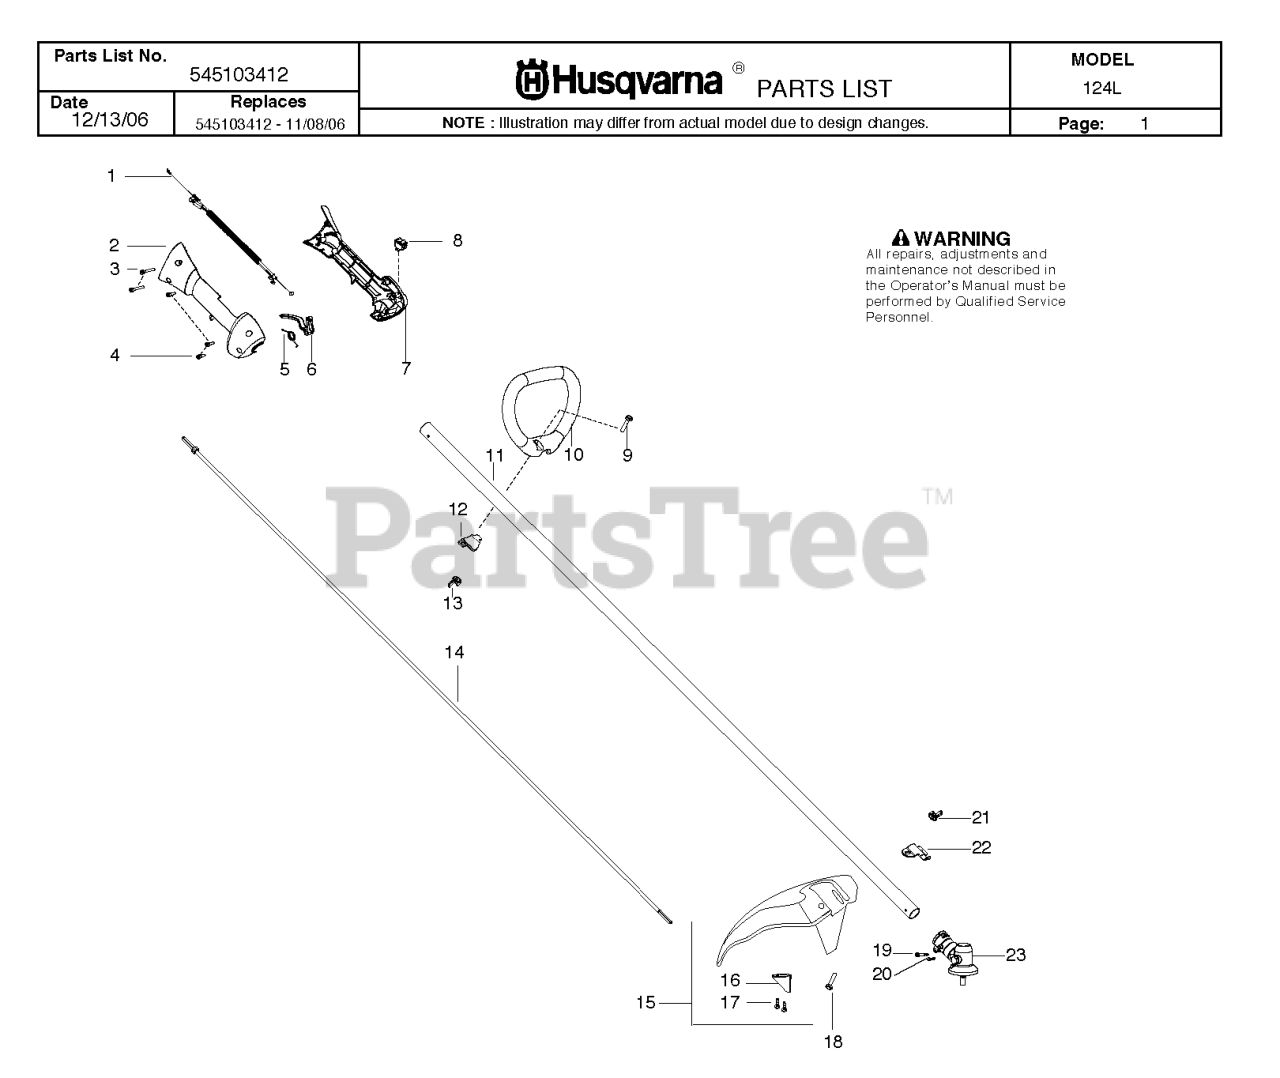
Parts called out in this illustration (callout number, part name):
1	Assy-Cable/Wire Harness
2	HOUSING-THROTTLE (RH)
4	SCREW M4 X 1.75 PT 16MM
5	SPRING TRIGGER
6	TRIGGER THROTTLE
7	HSG THROTTLE LH
8	KIT SWITCH
9	BOLT, TYPE 2
10	HANDLE ASSIST
11	KIT DRIVESHAFT SST
12	CLAMP ASSIST HANDLE
13	WINGNUT, TYPE 2
15	KIT-SHIELD
16	LINE LIMITER 17"
18	BOLT, TYPE 2
19	SCREW - CARB. ADAPTOR
20	SCREW 8-16 X 9/16 (PLAS
21	WINGNUT, TYPE 2
22	BRACKET SHIELD STRAIGHT SHAFT
